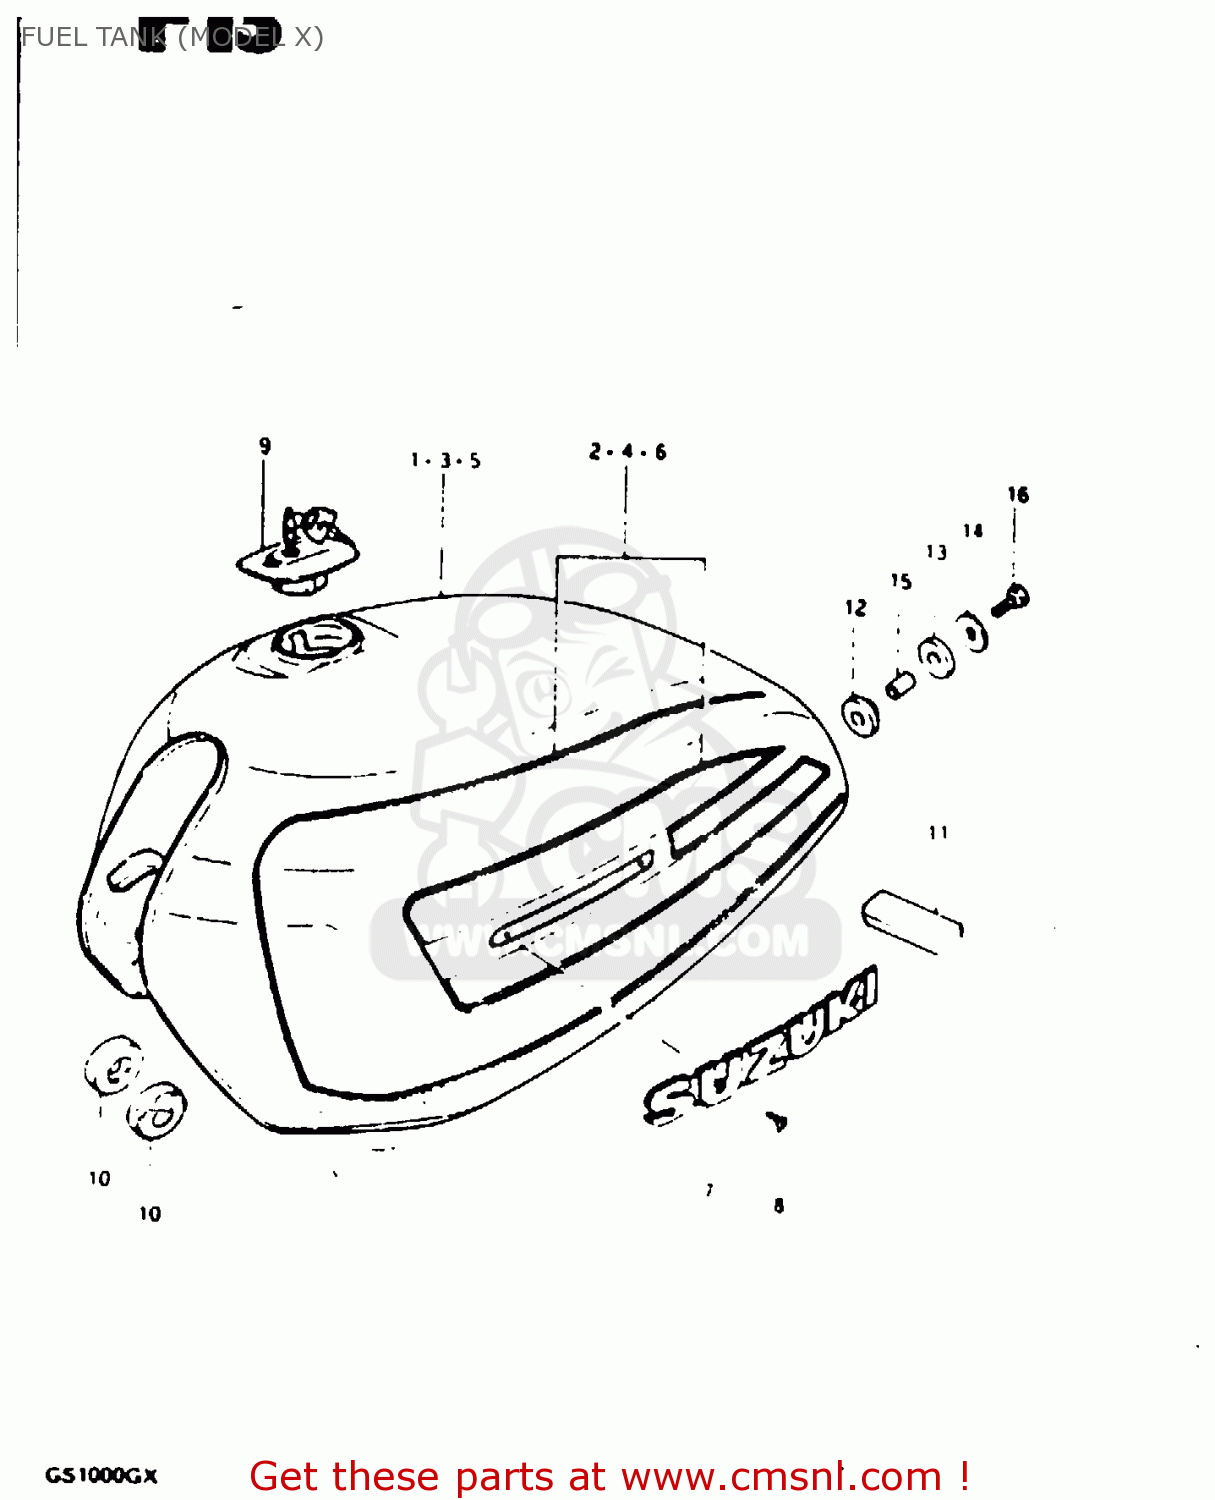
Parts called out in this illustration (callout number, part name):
1	TANK, FUEL (BLACK)
2	TAPE SET
3	TANK, FUEL (RED)
4	TAPE SET
5	TANK, FUEL (BLUE)
6	TAPE SET
7	EMBLEM,FUEL TANK
8	SCREW 3X6
9	CAP SET,FUEL TANK
10	CUSHION
11	CUSHION
12	CUSHION
13	CUSHION
14	WASHER (8.5X29X1.6)
15	SPACER(8.5X12X19)
16	BOLT (8X30)
